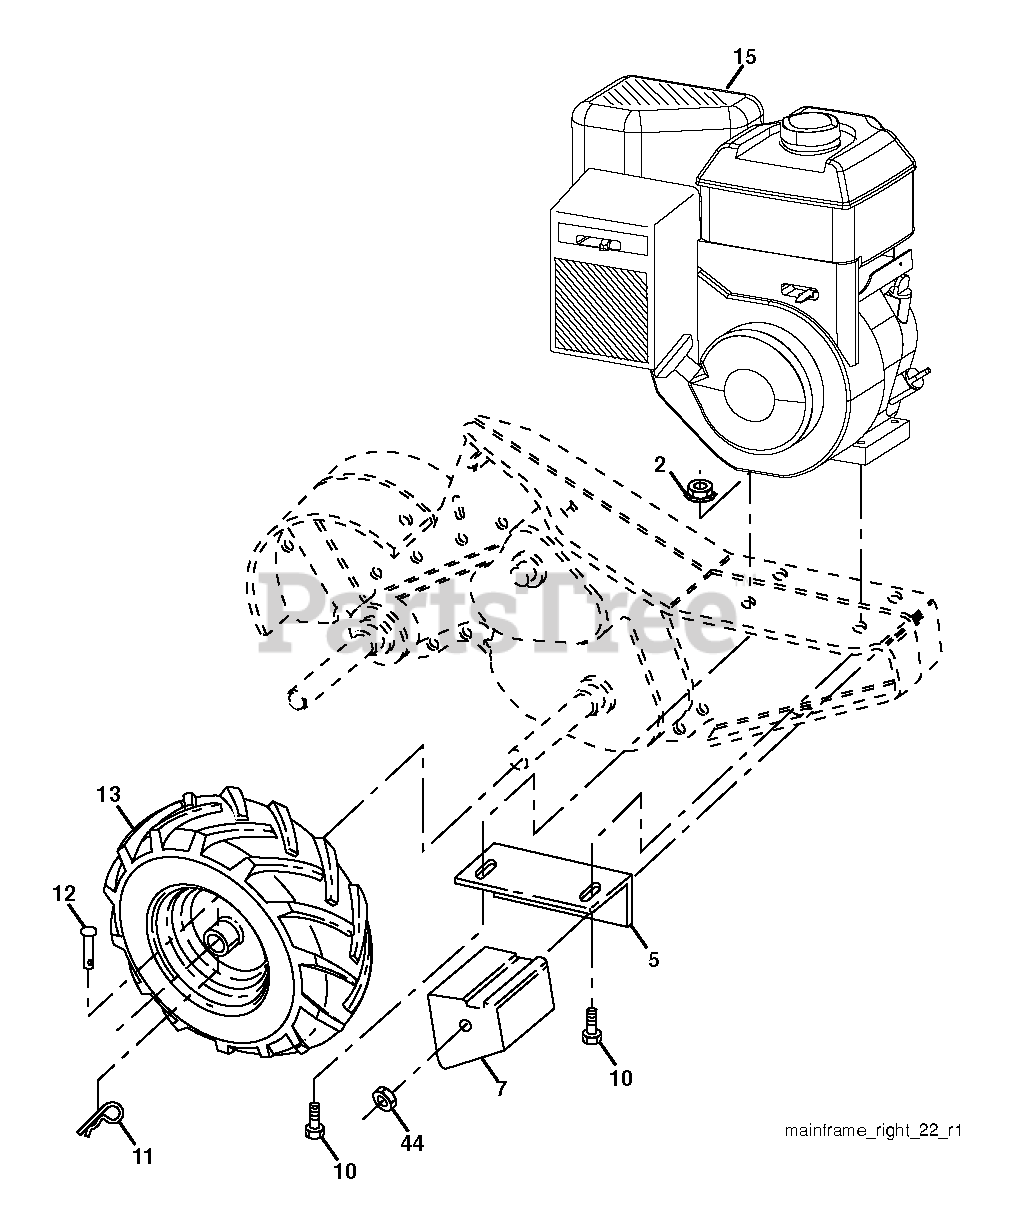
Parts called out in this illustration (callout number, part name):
2	LOCKNUT-FLANGE 5/16-18
5	BRACKET RH CRT
7	COUNTERWEIGHT, RH
10	BOLT
12	RIVET,DRILLED
13	TIRE.CHV.13X5-6
15	Poulan TBD
